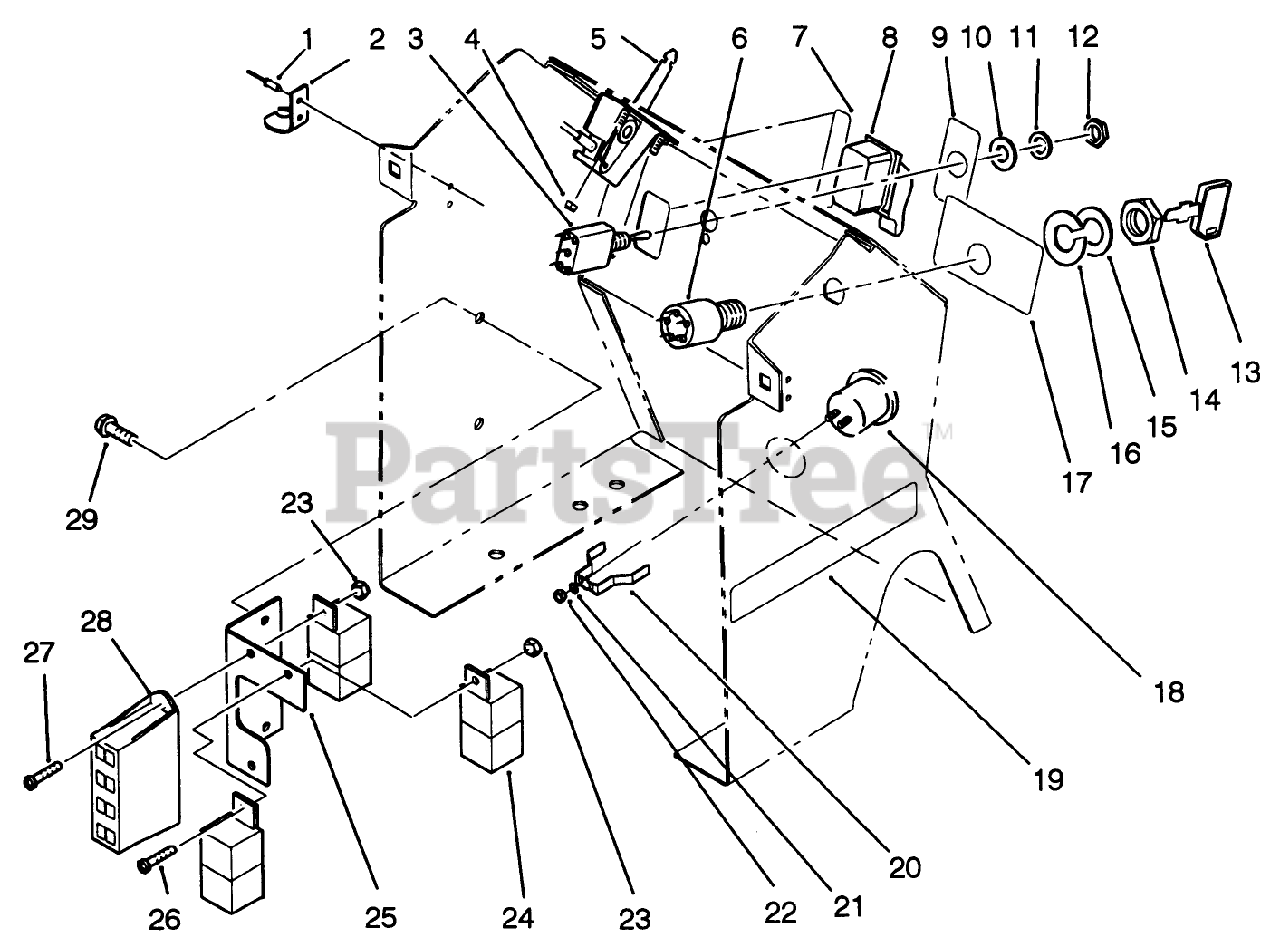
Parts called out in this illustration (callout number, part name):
2	KEEPER-LATCH
3	SWITCH-LIGHTS
5	CONTROL-THROTTLE
6	KEY SWITCH ASM
8	PTO-SWITCH W/COVER
9	DECAL-LIGHTS
10	TAB-WASHER
11	Washer
12	*DISC**
20	CLAMP-HOUR METER
21	WASHER-LOCK
24	RELAY
26	SCREW-PPH
27	SCREW
